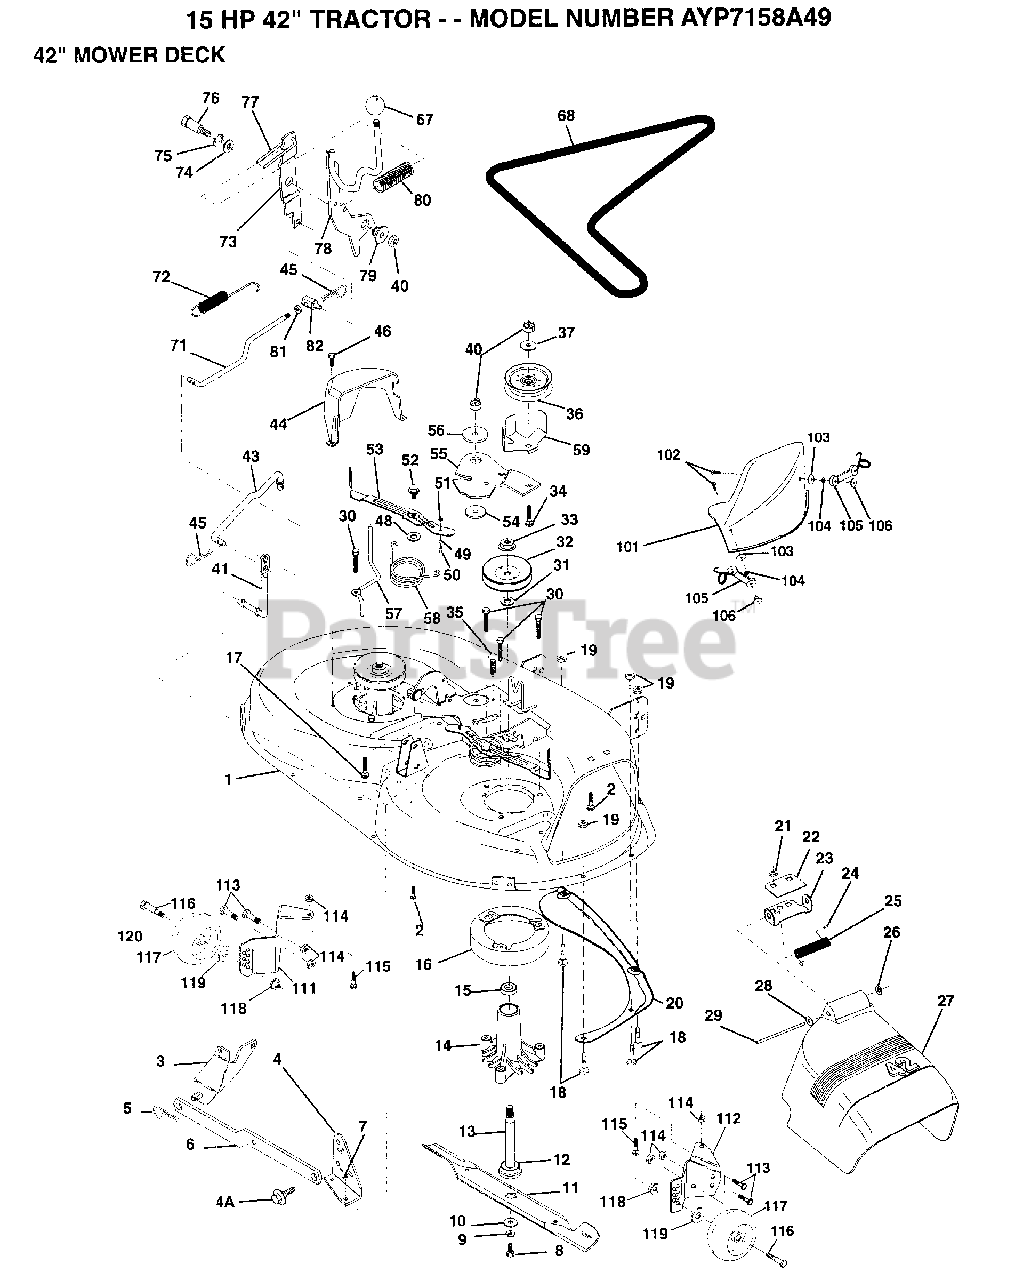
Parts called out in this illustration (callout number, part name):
2	BOLT
3	BRKT ASM SWAY BAR
4	BRKT DECK SW BAR
4A	BOLT SHD 5/16-18
7	NUT
8	BLADE BOLT
10	WASHER.HARD.BLADE
11	"BLADE.42"" MULCHER"
12	BEARING.BALL
14	HSG ASM MANDREL
15	BEARING
17	BOLT RDHD 3/8-16
18	BOLT
19	NUT
22	STIFFENER BRKT
23	DEFLECTOR BRKT
24	CAP-SLEEVE LT
25	SPRING TORSION
26	NUT PUSH M
27	DEFLECTOR.SHIELD
28	WASHER
29	HINGE ROD
31	WASHER
34	BOLT
35	XMAS TREE FASTNER
36	FLAT IDLER PULLEY
37	WASHER
41	PIVOT ROD
43	ROD CLUTCH W/NIBS
44	GUARD MAND LH BLK
45	RETAINER M
46	SCREW.1/4-20X5/8
48	HARD SMALL WASHER
50	SHOULDER BOLT
51	LOCKNUT
52	BOLT.SHLD.5/16-18
53	BRAKE PAD ARM ASM
54	HARDENED WASHER
56	SPACER RETAINER
57	KEEPER BELT LH 42
58	SPRING TORSN BRAK
59	GUARD IDLER TUV
60	BELT-V MWR 82.625
71	ROD CLUTCH 38/42
72	RETURN SPRING
73	CLUTCH ARM SECOND
74	WASHER
75	RING
76	SHOULDER BOLT
77	SPRING KEEPER
78	LEVER ASM CLT PRM
79	BUSHING
81	NUT
82	TRUNION
83	KNOB T (1/2-HOLE)
101	"COVER.MULCH.42"""
102	WASHER #10
103	LOCKWASHER
104	SCREW
113	BOLT
116	BOLT.SHOULDER
117	WHEEL GAGE DONUT
118	NUT SPECIAL T
119	WASHER
